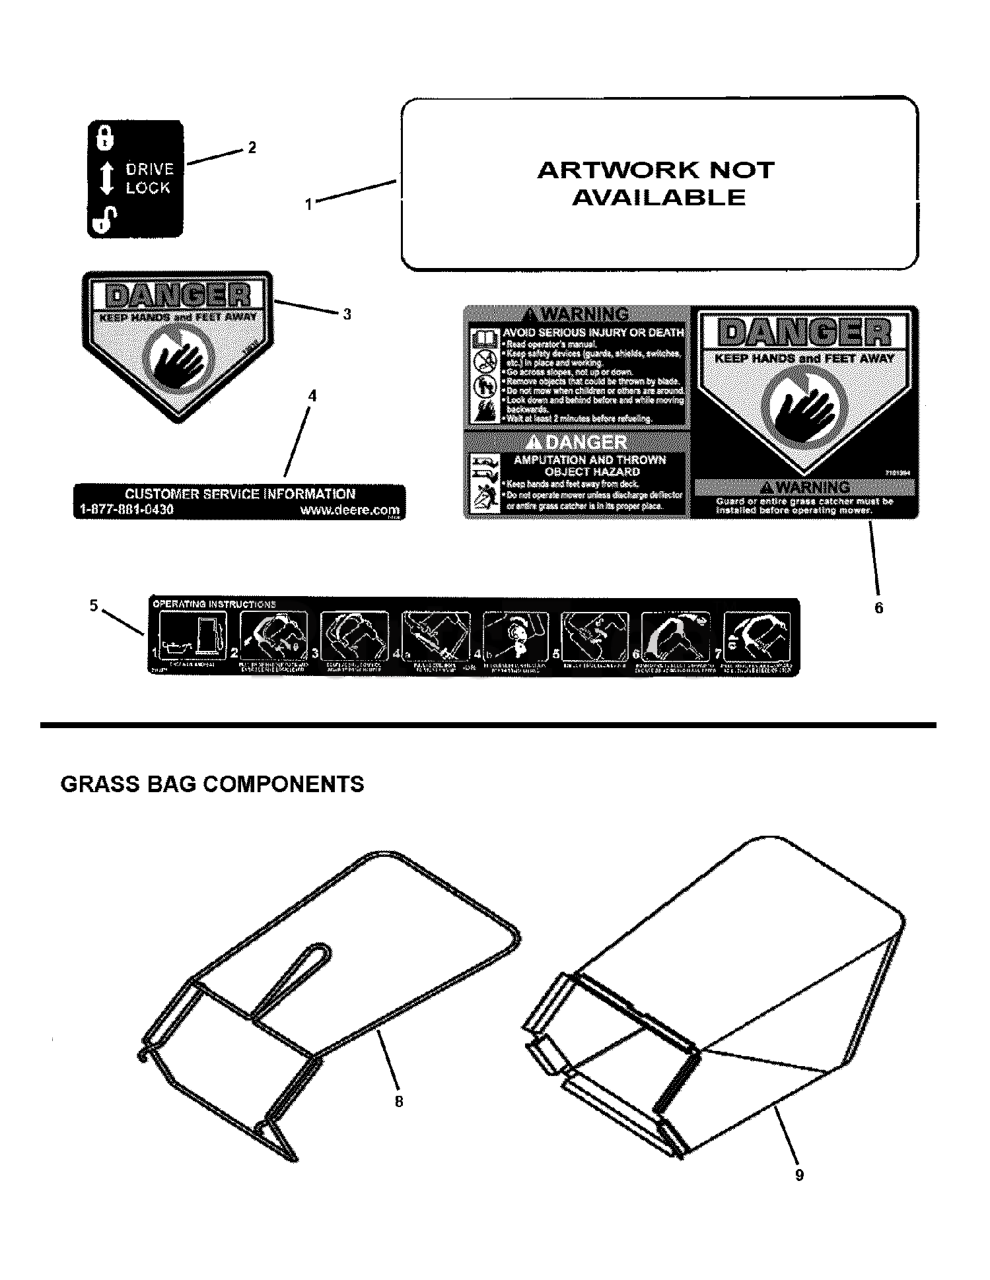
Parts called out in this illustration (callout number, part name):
1	DECAL, JS36 MOWMENTUM
2	DECAL, NEUTRAL LOCK
3	DECAL, DANGER, CUT FINGER
4	DECAL, CUSTOMER SERVICE, MY08, DEERE
5	DECAL, OPERATION, JD
6	DECAL, WARNING, REAR DISCHARGE DOOR
8	BAG FRAME, RD
9	BAG, GRASS, 22" REAR DISCHARGE
